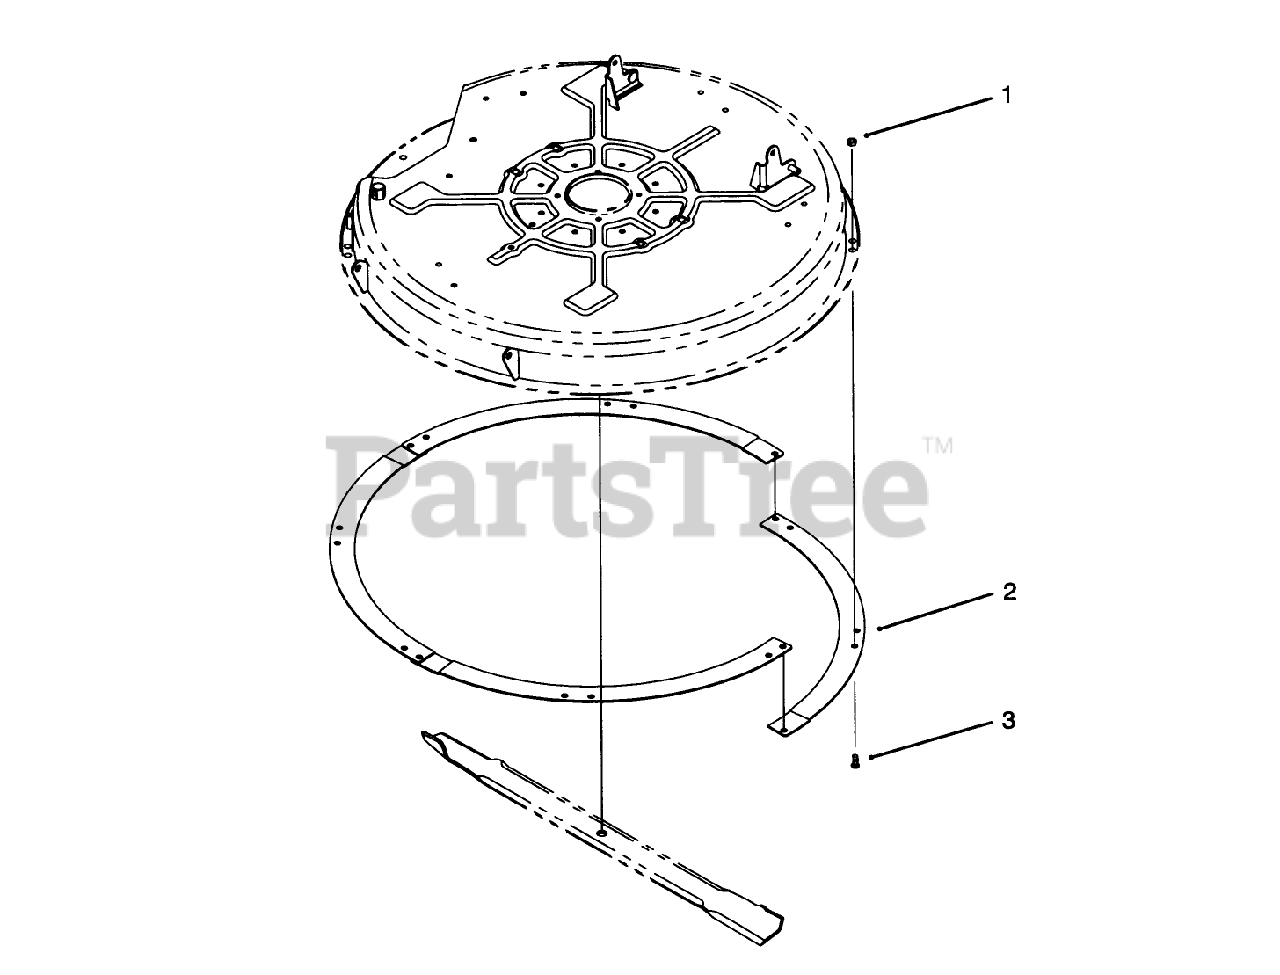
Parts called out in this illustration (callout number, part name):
1	NUT-LOCK, NI
2	Ring-Deck
3	SCREW-PPH
